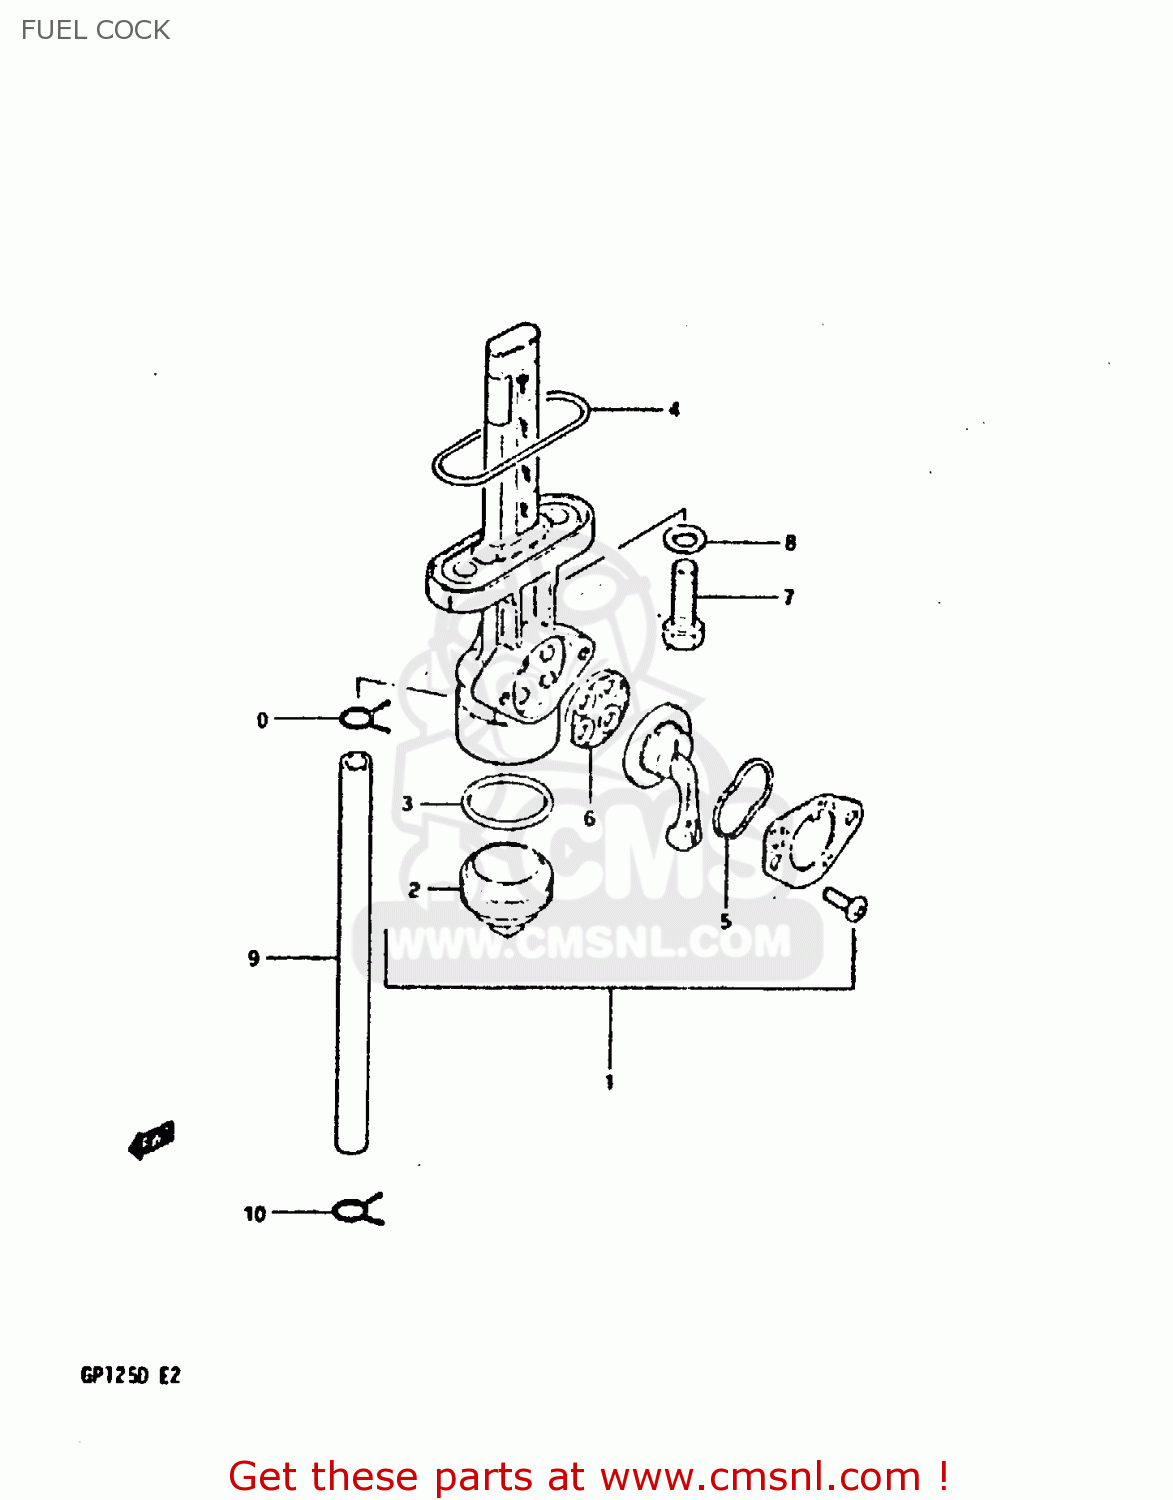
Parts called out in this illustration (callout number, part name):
1	COCK ASSEMBLY,FUEL
2	CUP,FUEL COCK
3	GASKET,FILTER (NAS)
4	O RING,FUEL COCK
5	WASHER,LEVER
6	GASKET,LEVER (NAS)
7	BOLT(6X20)
8	GASKET
9	HOSE
10	CLIP
